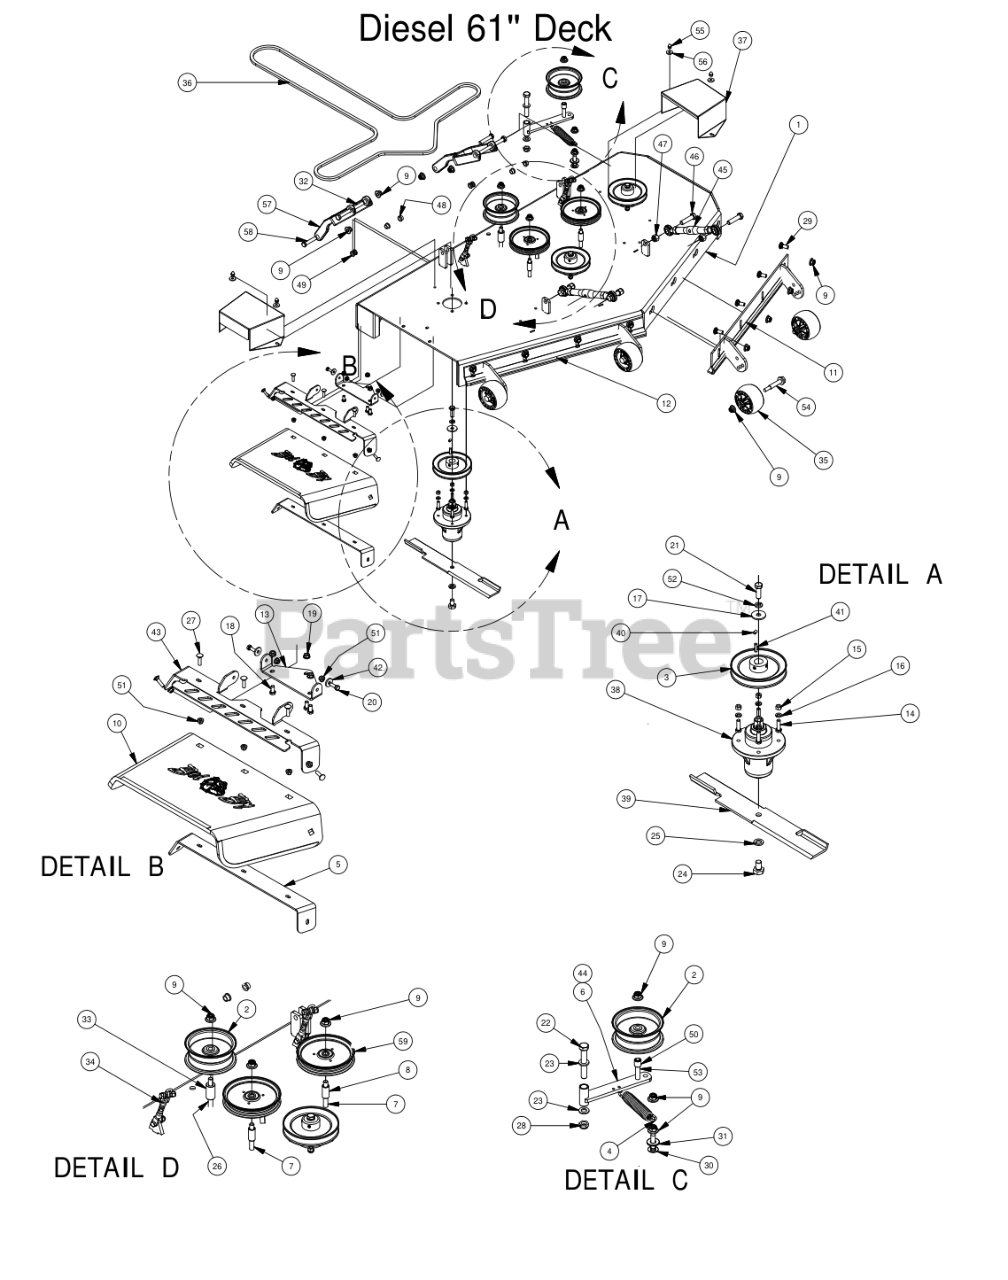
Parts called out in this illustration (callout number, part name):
1	61" AOS Deck
2	5 3/4" Deck Idler Pulley
3	6 1/4" Drive Pulley
4	2015 Deck Idler Spring Outlaws
5	60" Discharge Lower Bracket
6	Deck Idler
7	1/2 x 3 1/2 Flange Bolt Grade 8
8	.502 ID X.750 OD X 1.500 Long Spacer
9	1/2-13 Nylon Insert Flange Nut
10	Rubber Discharge Chute
11	61 Outlaw Adjustable Deck Front (Left)
12	61 Outlaw Adjustable Deck Front (Right)
13	Discharge Chute Hanger (deck mounted)
14	3/8" x 1 1/4" Hex Bolt
15	3/8-16 Hex Nuts Zinc
16	3/8 Lockwasher Zinc
17	1/2 Belleville Washer
18	3/8" x 3/4" Hex Bolt
19	3/8" Flange Nut
20	5/16" x 1" Bolt
21	1/2"-20 x 1 1/2 - Grade 5 Fine Thread Bolt
22	5/8" x 4" Hex Bolt
23	.630 ID Plastic Washer
24	5/8" x 1 1/2" Grade 8 Hex Bolt (Fine)
25	5/8" Lock Washer
26	1/2" x 4" Bolt (Grade 8)
27	5/16" x 1 1/4" Carriage Bolt
28	5/8-11 Nylon Insert Jam Half Nut
29	1/2" x 1 1/4 Carriage Bolt
30	1/2 x 2" Carriage Bolt
31	.517 Square Hole Round Washer
32	1/2" x 5 1/2" Bolt
33	1 3/4" Pulley Spacer
34	4-Link Adjustable Deck Hange
35	Anti-Scalp Rollers
36	B236 Belt - Diesel EZ Ride
37	Pulley Cover
38	Double Bearing Spindle
39	61 inch Fusion Blade
40	5/16 Set Screw
41	1/4" x 1" Key
42	.360 ID Plastic Washer
43	60" Discharge Chute Upper Hanger
44	Deck Idler Assembly-parts of Assembly 4,9,12,63,67
45	Turnbuckle (Top Link)
46	5/8" x 2 1/2" Grade 5 Hex Bolt (Coarse)
47	5/8 Std NC Nylock Nut
48	Flange Bushing For Upper Deck Arm
49	Flange Bushing For Lower Deck Arm
50	Spacer 3/4 OD x 1/2 ID x 3\4 Length
51	5/16" Nylon Flange Nut
52	1/2" Lock Washer
53	1/2-13 x GR 5 Hex Bolt Zinc
54	Deck Wheel Bolt
55	Acorn nut-pulley Cover
56	.360 ID Plastic Washer-Black
57	Deck Arm Assembly
58	1/2" x 3" Hex Bolt
59	5-3/4 Idler Pulley-Capitol Stampings
